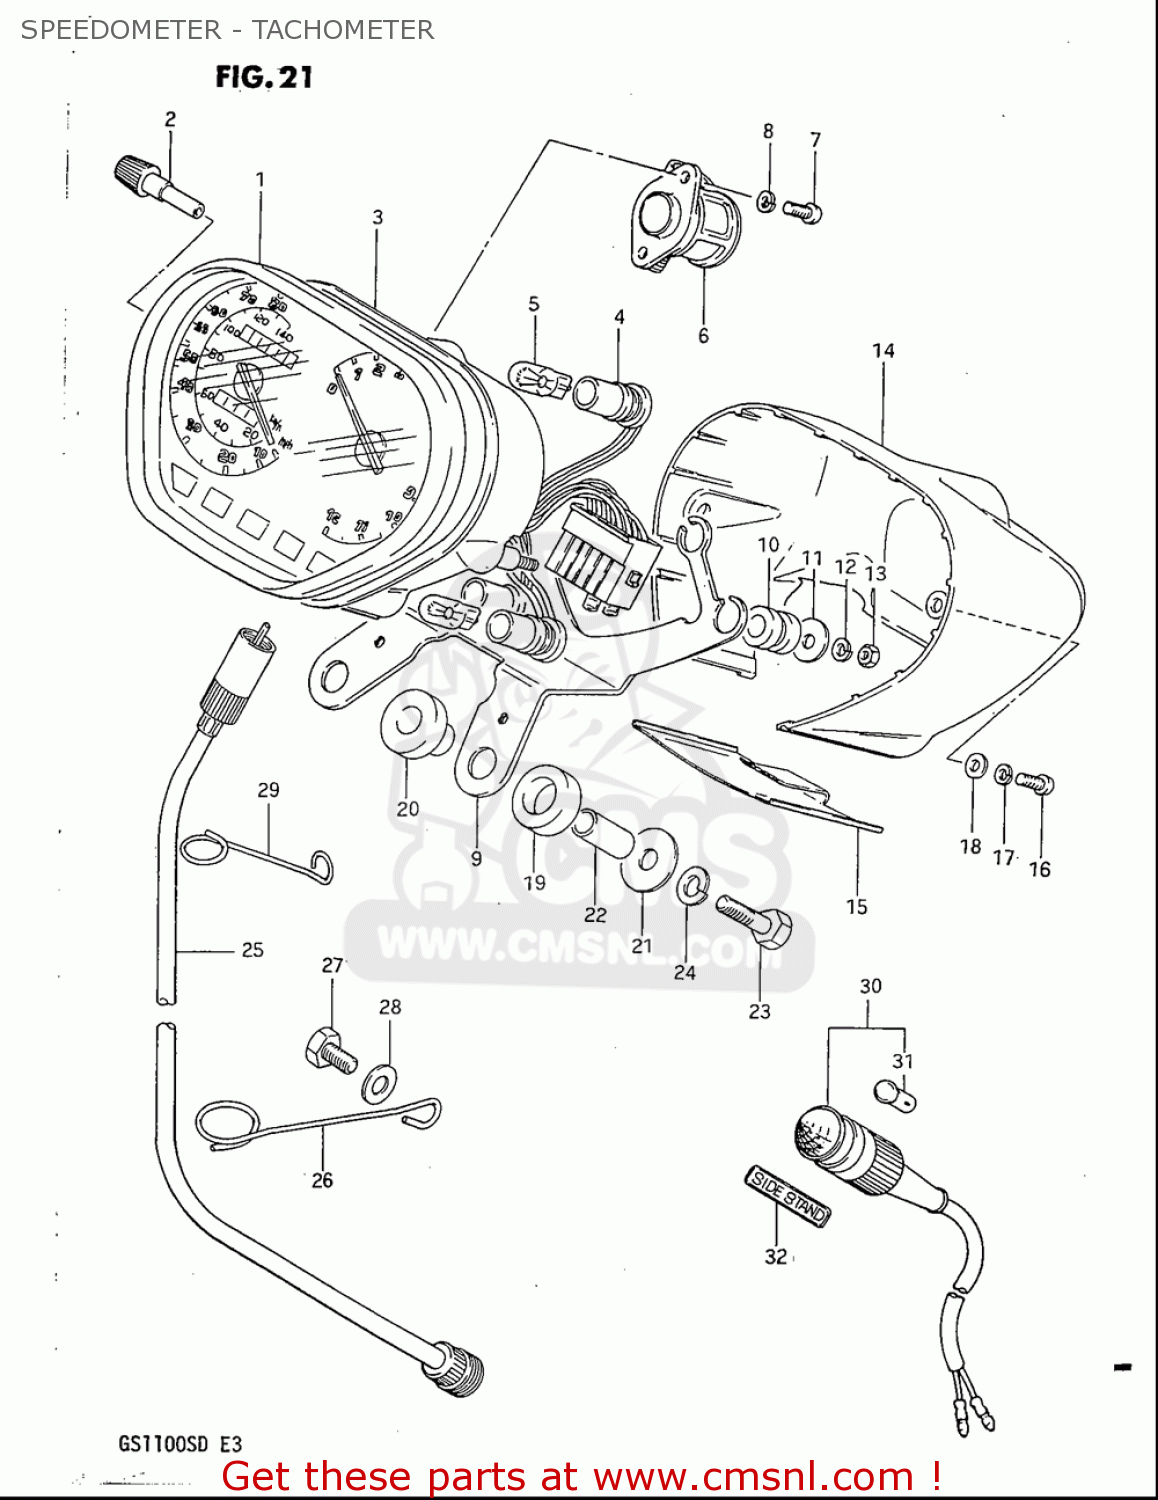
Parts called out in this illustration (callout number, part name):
1	METER,SPEED/TACHO
2	KNOB,TRIP METER
3	CUSHION
4	SOCKET
5	BULB(12V3.4W,T10,BF175-01450A)
6	GEAR BOX,SPEEDOMETER
7	SCREW
8	WASHER,LOCK
9	BRACKET,METER
10	CUSHION
11	WASHER(4.5X16X1.2)
12	WASHER,LOCK
13	NUT
14	COVER,LWR
16	SCREW
17	WASHER,LOCK
18	WASHER
19	CUSHION
20	CUSHION
21	WASHER(6.5X24X1.6)
22	SPACER(6.1X8X15.5)
23	BOLT
24	WASHER,LOCK
25	CABLE ASSY,SPEEDOMETER
26	CLAMP,SPEEDOMETER CABLE
27	BOLT
28	WASHER
29	GUIDE,SPEEDOMETER CABLE UPR
31	BULB(12V3.4W,STANLEY,A72A)
